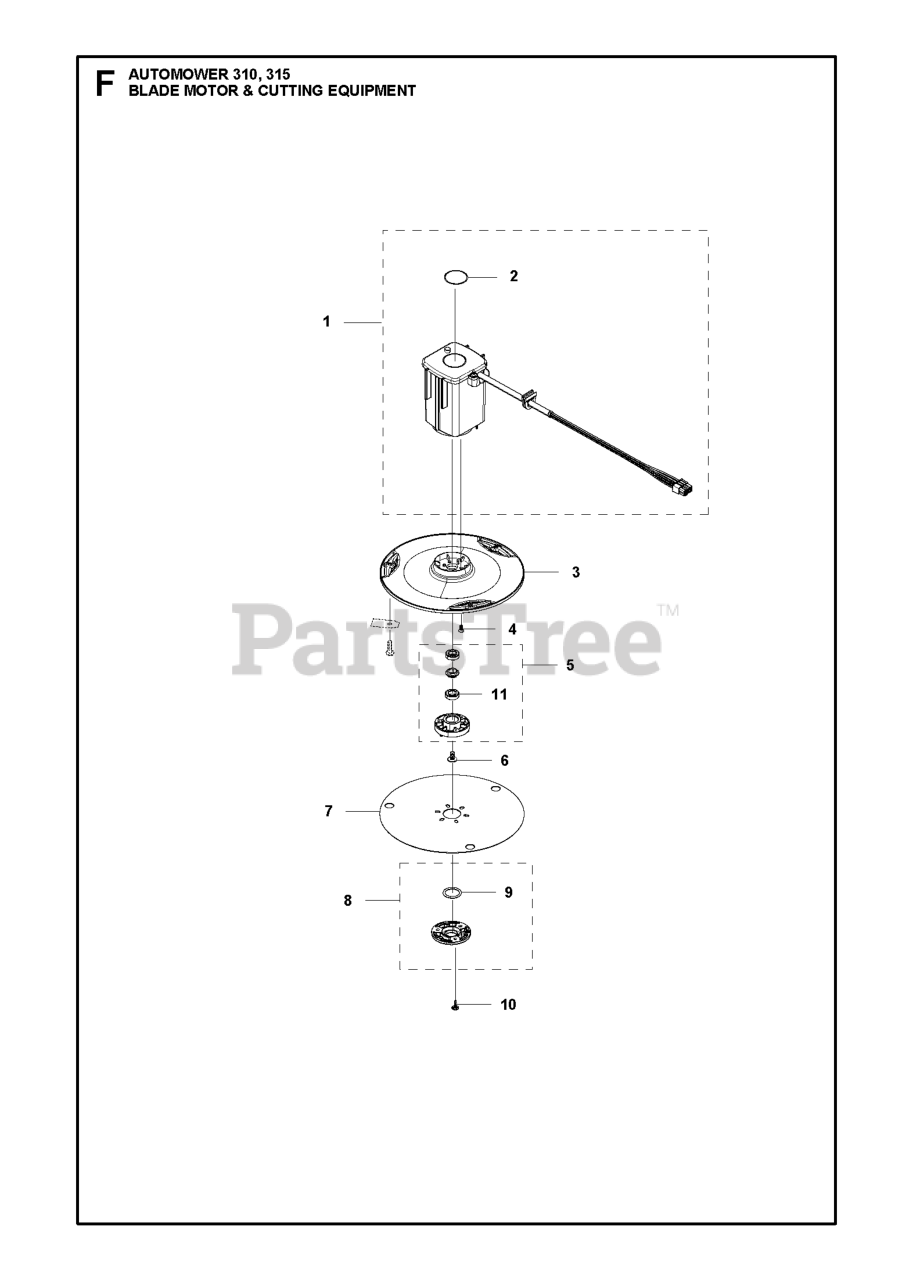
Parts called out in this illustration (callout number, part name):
1	MOTOR ASSY
2	KIT AIR FILTER KIT 305 - 10 PC
3	CUTTING DISC CUTTING WIDTH 22
4	SCREW TORX M4X8 8.8 NYLON PATC
5	BEARING HOUSING ASSY
6	SCREW
7	SKID PLATE
8	COVER KIT BEARING
9	O-RING 20X2,5 MM
10	SCREW 14MM
11	BALL BEARING BALL BEARING 535
11	BALL BEARING 2 RS,TIGHT CLEAR
